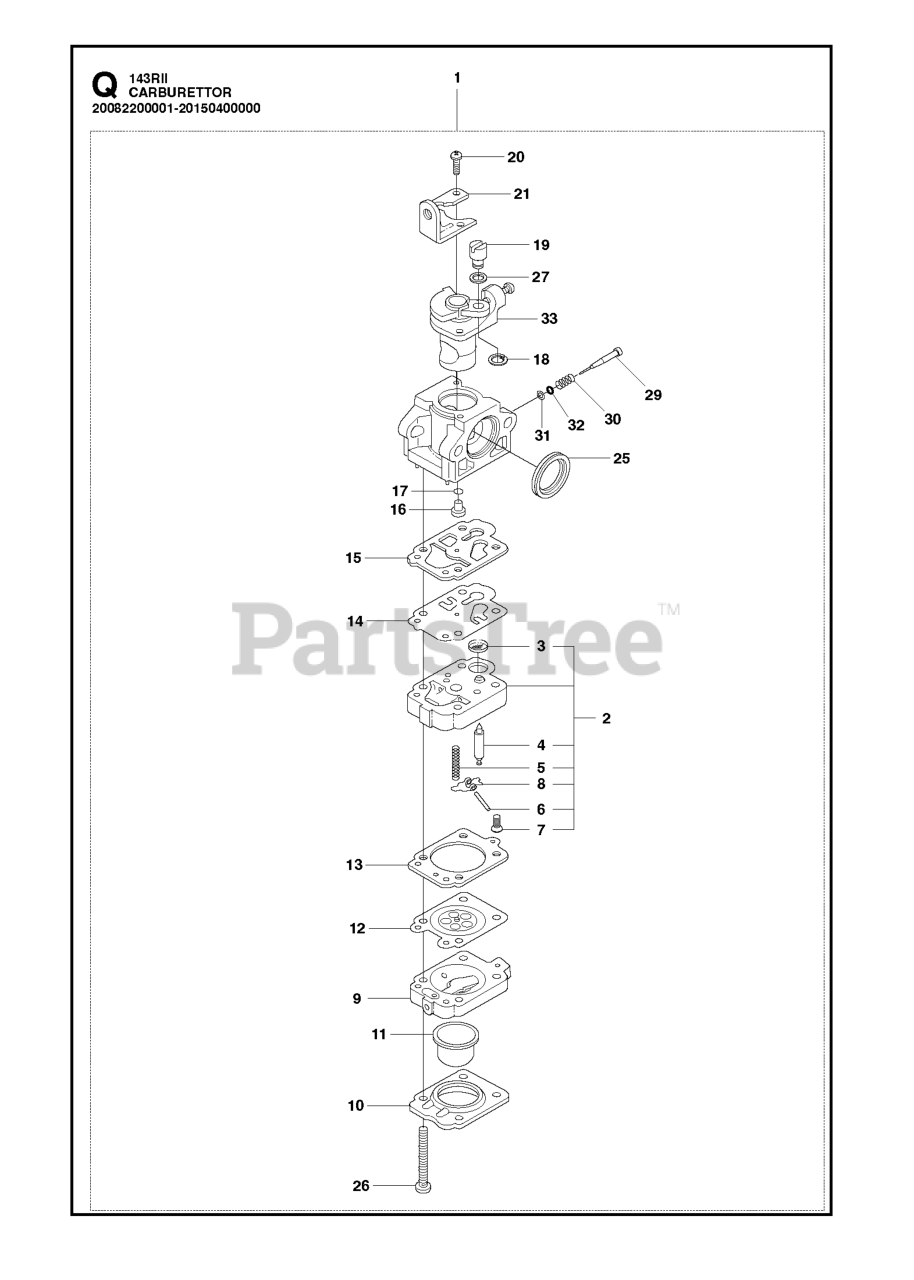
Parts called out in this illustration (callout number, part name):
2	CARBURETOR BODY
3	SCREEN
4	VALVE INLET
16	JET #45
17	O-RING
25	RING PACKING
29	NEEDLE
30	SPRING
31	O-RING
32	WASHER
33	VALVE-A
